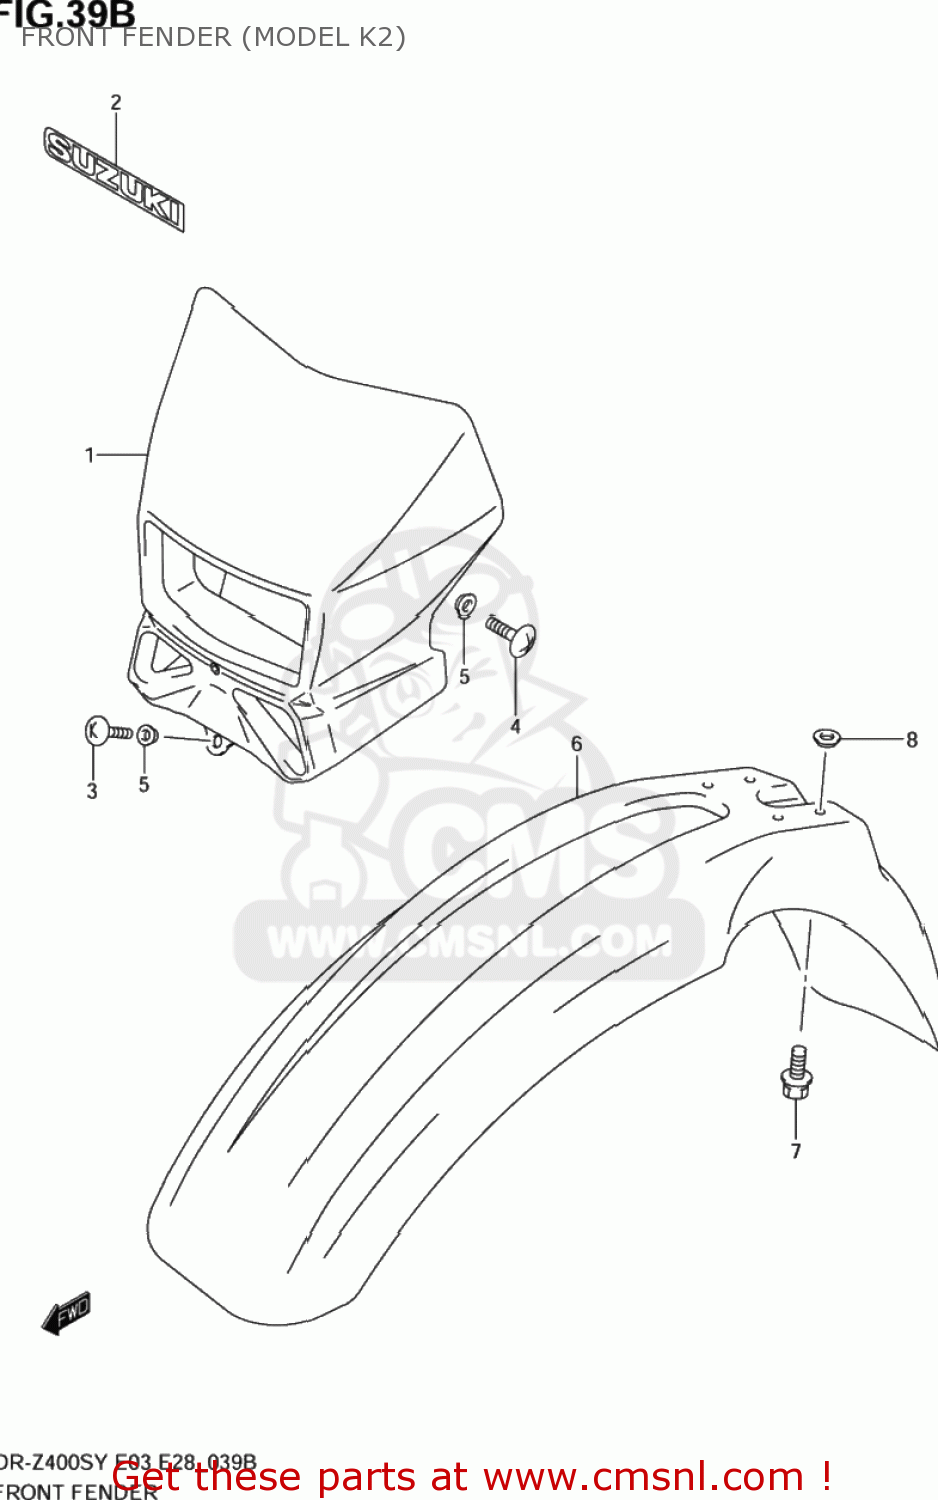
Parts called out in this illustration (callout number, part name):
1	COVER,HEADLAMP
2	EMBLEM,SUZUKI
3	SCREW 5X12
4	SCREW 6X12
5	WASHER
6	FENDER,FR
7	BOLT(6X16)
8	WASHER
